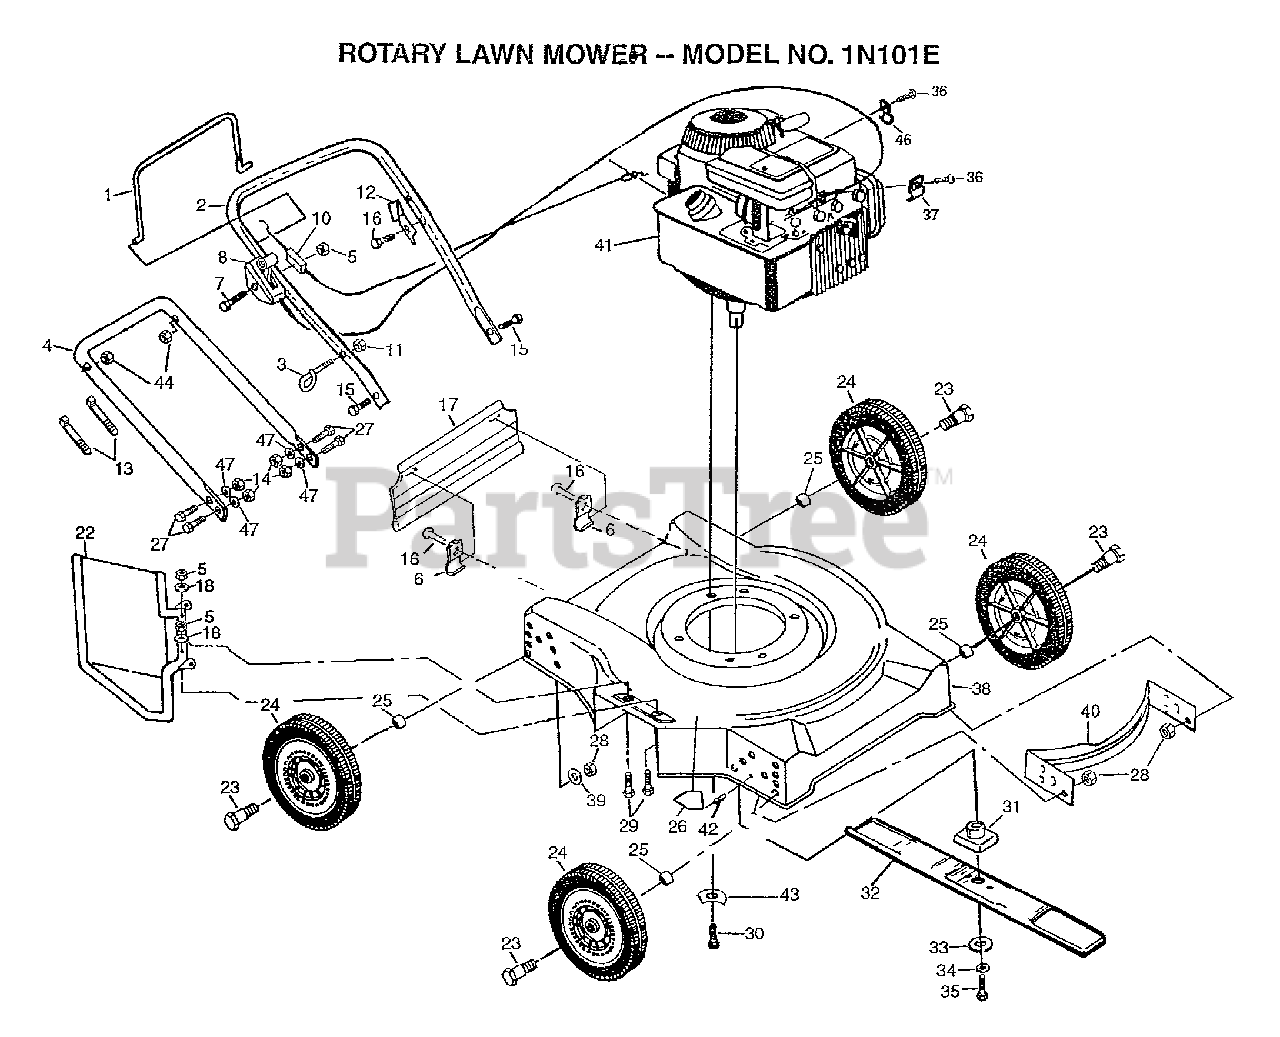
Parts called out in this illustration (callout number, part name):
1	CONTROL BAR PM
2	UPPER HANDLE
3	ROPE GUIDE
4	HANDLE LWR PM
6	"BRKT,DEFL PM"
7	SCREW.HXHD.WASH.
10	CABLE.CONT.ENG
12	"BRKT,UPSTOP"
14	LOCKNUT
15	BOLT 1/4-20-1 1/2
16	TAPPING SCREW
17	SKIRT.REAR.20RD.
22	"GRD,DISCHARGE"
23	AXLE BOLT
24	WHEEL ASSY
26	DECAL HYT
28	LOCKNUT PM
29	BOLT LT
30	BOLT.ENG.3/8-16
31	BLADE ADAPTOR
32	BLADE.20.MULCH.AY
33	"WASHER,HARDEN"
34	LOCKWASHER
35	SCREW
36	SCREW PM
37	CABLE CLAMP
42	BLIND RIVET
46	GUIDE CLIP PM
47	STEEL WASHER
